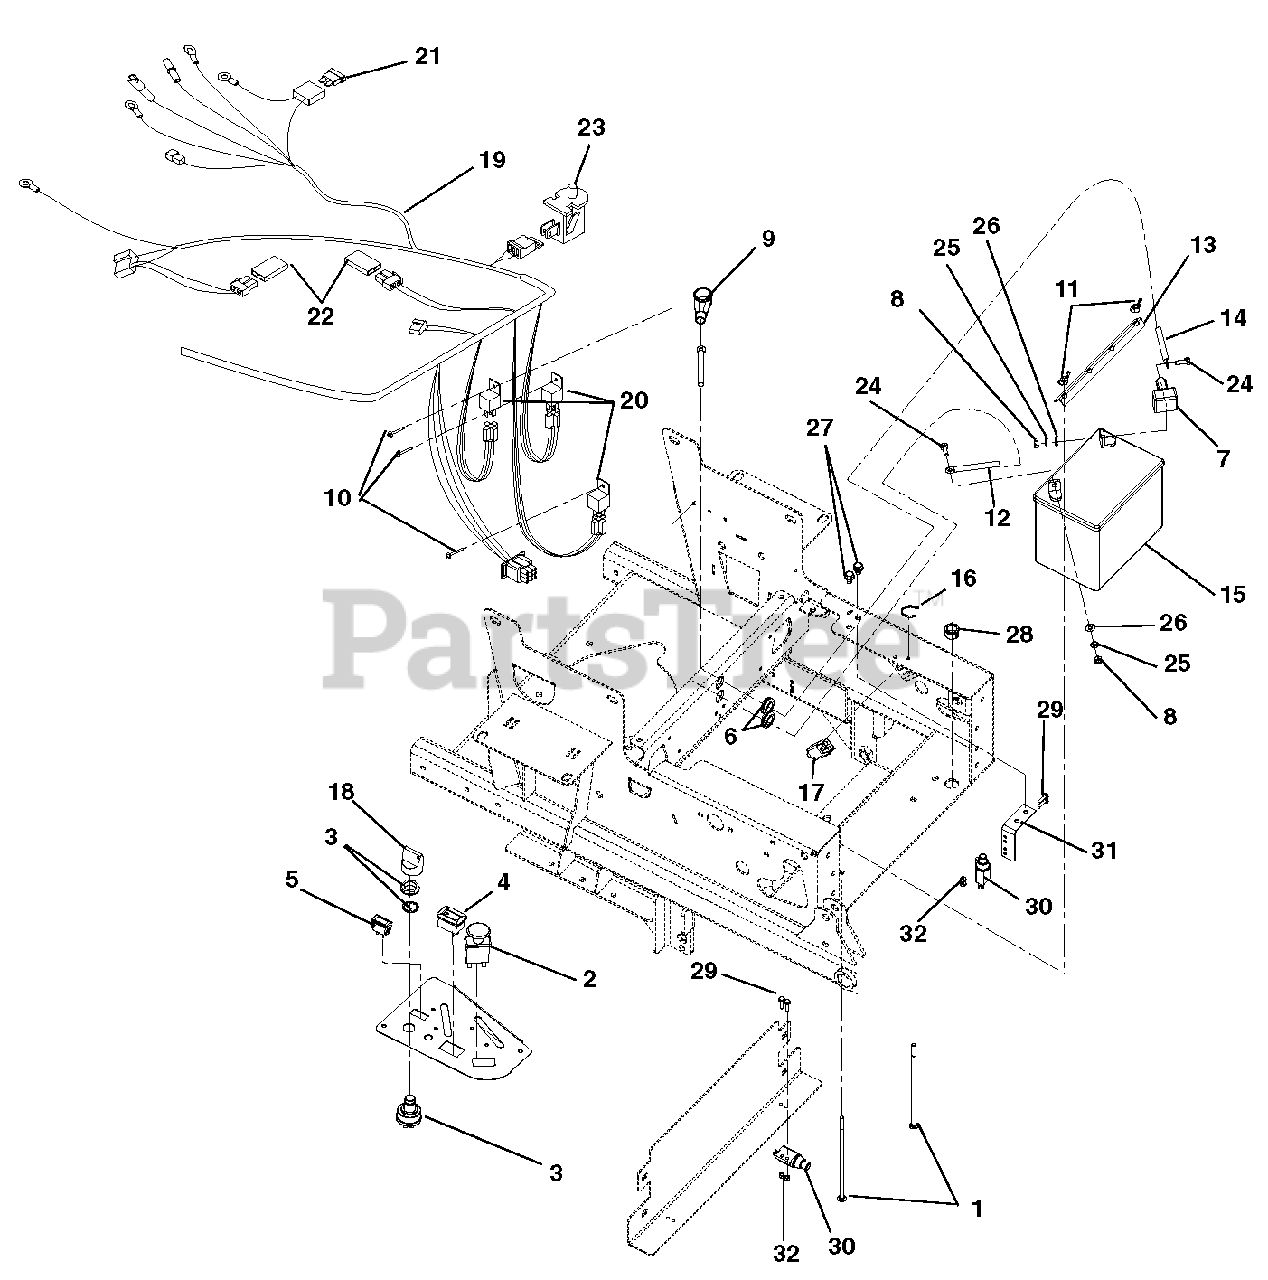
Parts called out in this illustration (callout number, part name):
1	Bolt, Round Head Square Neck .25-20 x 7.50
2	Switch, Clutch
3	Switch, Ignition
4	Hour Meter w/Maintenance
5	Light, Indicator
6	Grommet, Rubber 5/8 ID/1.13
7	Insulator
8	Nut, Hex .25-20
9	Battery Terminal Boot, Red
10	Rivet, .25 Nylon Panel
11	Nut, Locking Wing .250-20
12	Ground Cable .31 x 22.00 x .31
13	Hold Down
14	Cable, Positive Battery 26.00"
15	Exide Battery Sealed Maintenance Free U1-250
16	Cable Tie
17	Switch, Snap In- N.O./N.O.
18	Key, with Shield
19	Harness, Wire- IZ, CZ, 100I
20	Relay,Sealed w/Diode
21	Fuse, 30 AMP.
22	Diode, Connector Shell
23	Switch, Snap Mounting (N.O.)
24	Bolt, Hex .25-20 x .75 Grade 5
25	Washer, Locking .25 x .062 Regular
26	Washer, Flat-STL.281 x .62 x .065
27	Screw, Tapping .31-18 x .50 Hex Washer Head
28	Bushing, Panel Snap .687 x .875 x .56
29	Screw, Machine 10-24 x .75 Hex Washer Head
30	Switch, Single Pole (N.O.) with Cover
31	Mount, Switch
32	Nut, Locking-Nylon 10-24 with Insert
